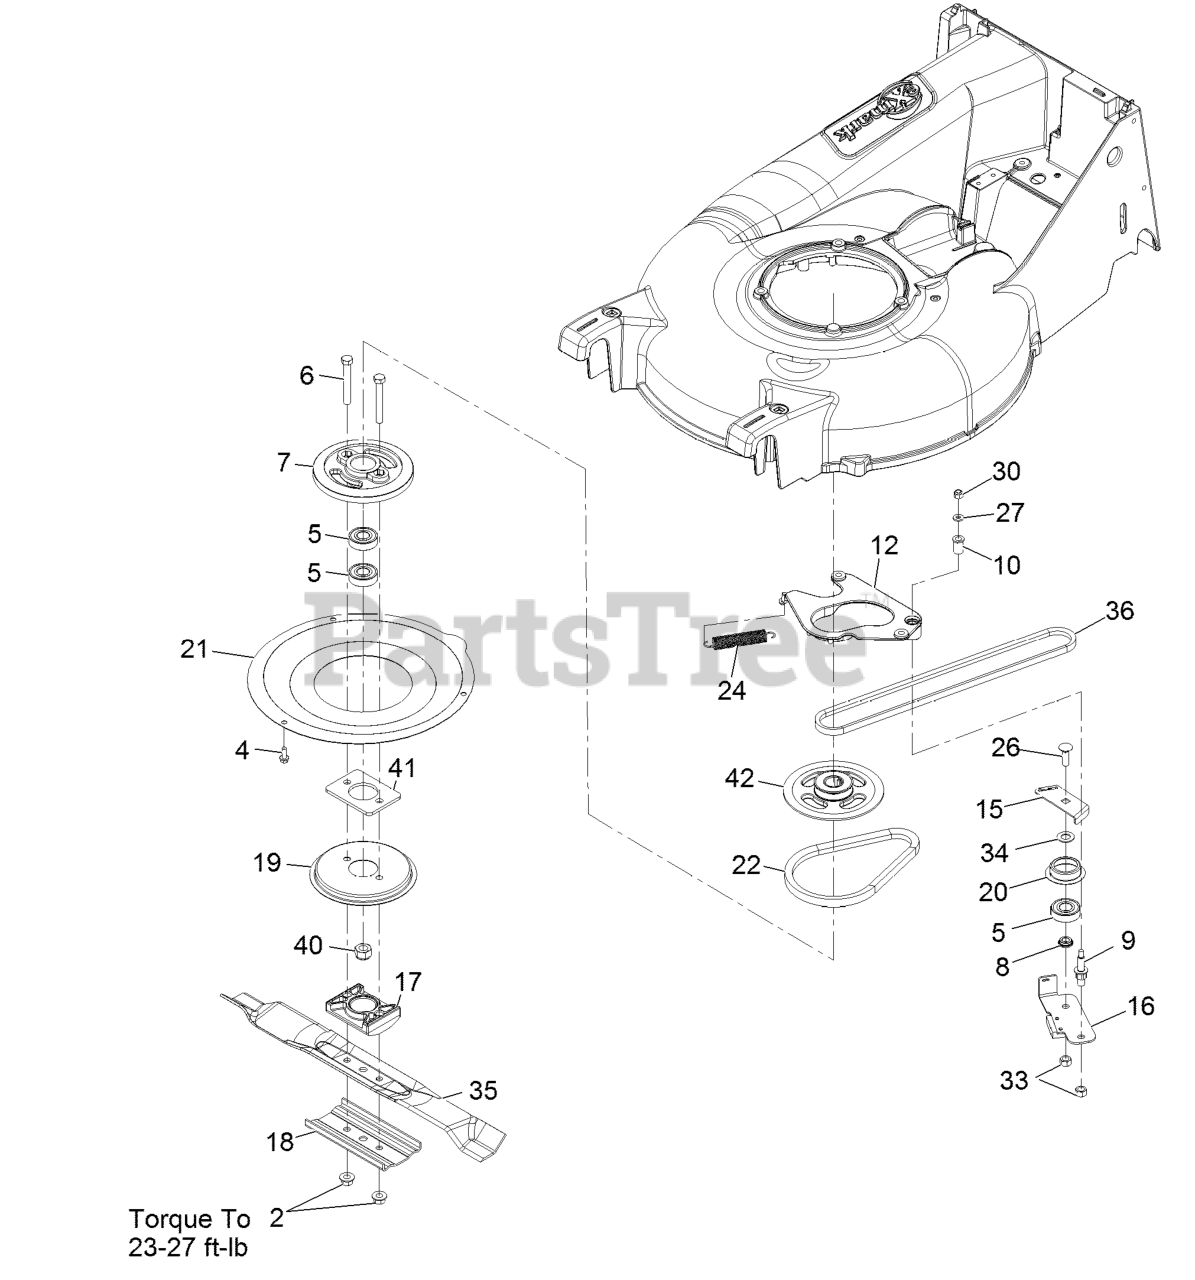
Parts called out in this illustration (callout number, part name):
2	Nut-Hex 3/8-24 Lock
4	SCREW-HWH
6	SCREW-HH
8	SPACER-BEARING
9	BOLT-SHOULDER
10	BUSHING
12	PLATE,ANCHOR
15	PLATE-GUIDE
17	SUPPORT-BLADE
18	SUPPORT-BLADE
19	DISC
20	RETAINER-BELT
21	COVER-BBC
22	BELT
24	SPRING-TENSION, BRAKE
26	SCREW-CARR
27	WASHER-FLAT
30	NUT-LOCK, NI
33	LOCKNUT
34	SPACER
36	BELT,3L P21 DRIVE
40	NUT-HEX
